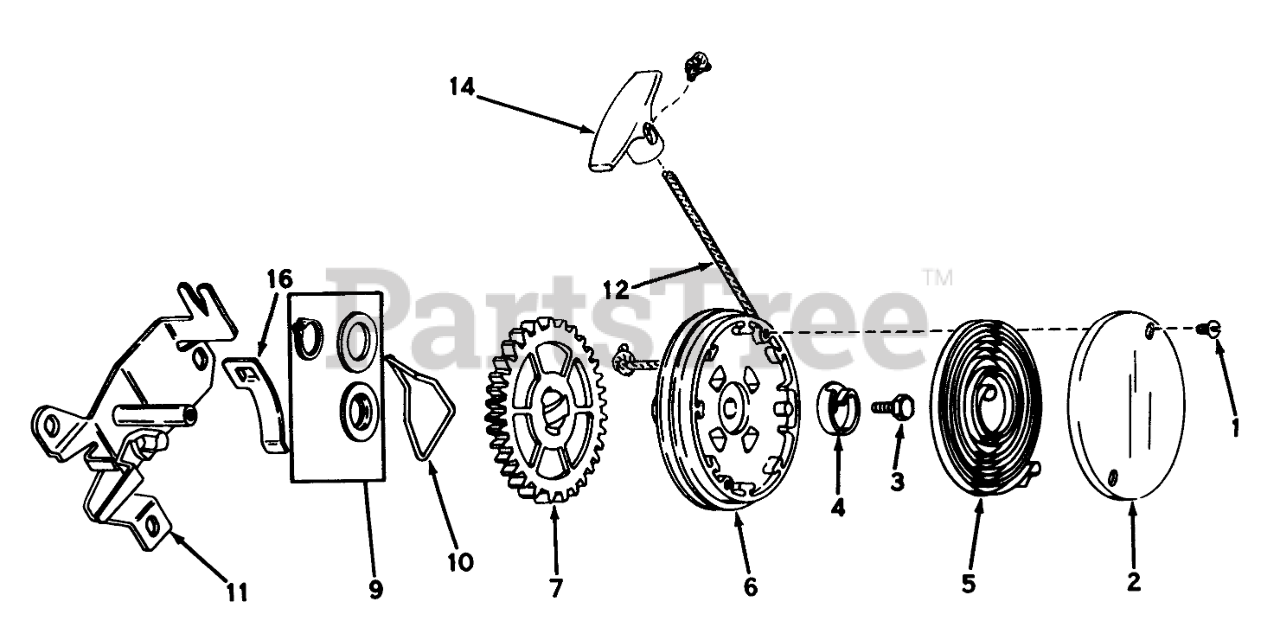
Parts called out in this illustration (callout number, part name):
2	Cover, Spring
3	Screw, Hex Washer Head
4	Hub Spring
5	Spring, Rewind
6	Pulley Assy. (Incl. #9)
9	Kit, Thrust Wash. & Snap Rg.
11	Bracket Assy., Mounting
12	Rope-Starter
14	Handle-Starter
16	Clip Rope
